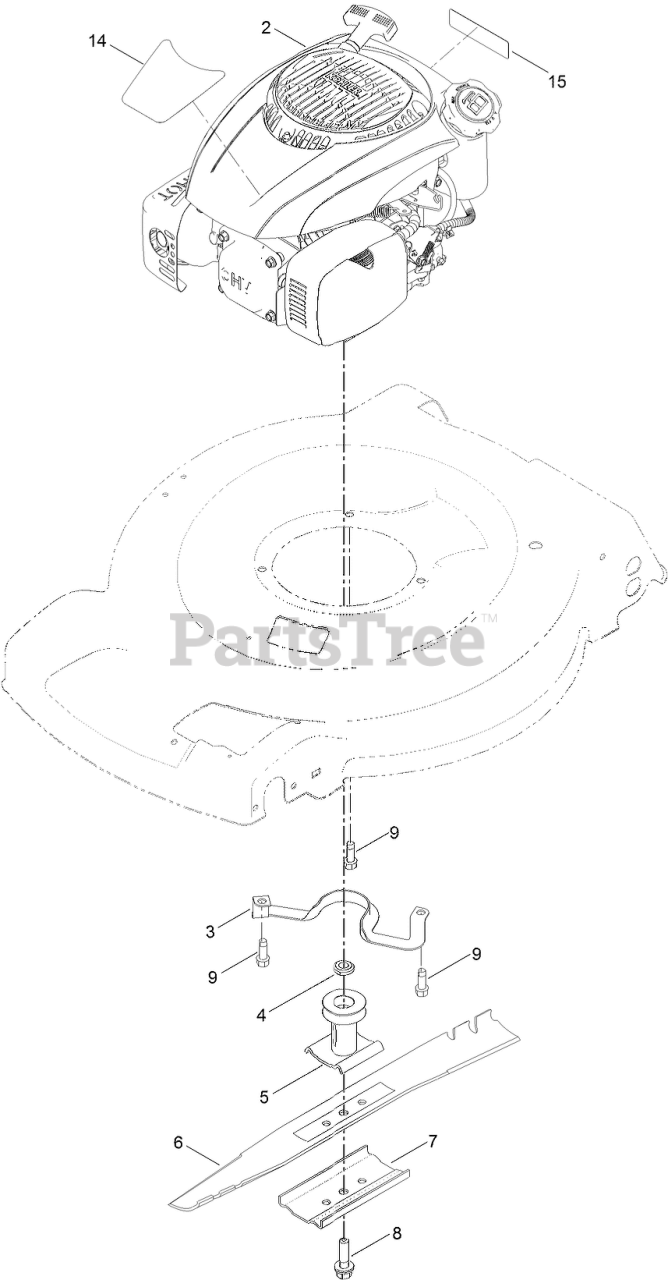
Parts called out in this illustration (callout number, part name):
3	Guide-Belt
4	Spacer-Driver
5	DRIVER-BLADE
6	BLADE-22 INCH
7	SUPPORT-BLADE
8	BOLT-BLADE
9	SCREW-TAPTITE
14	DECAL-SHROUD
15	DECAL-ARRESTER, SPARK
